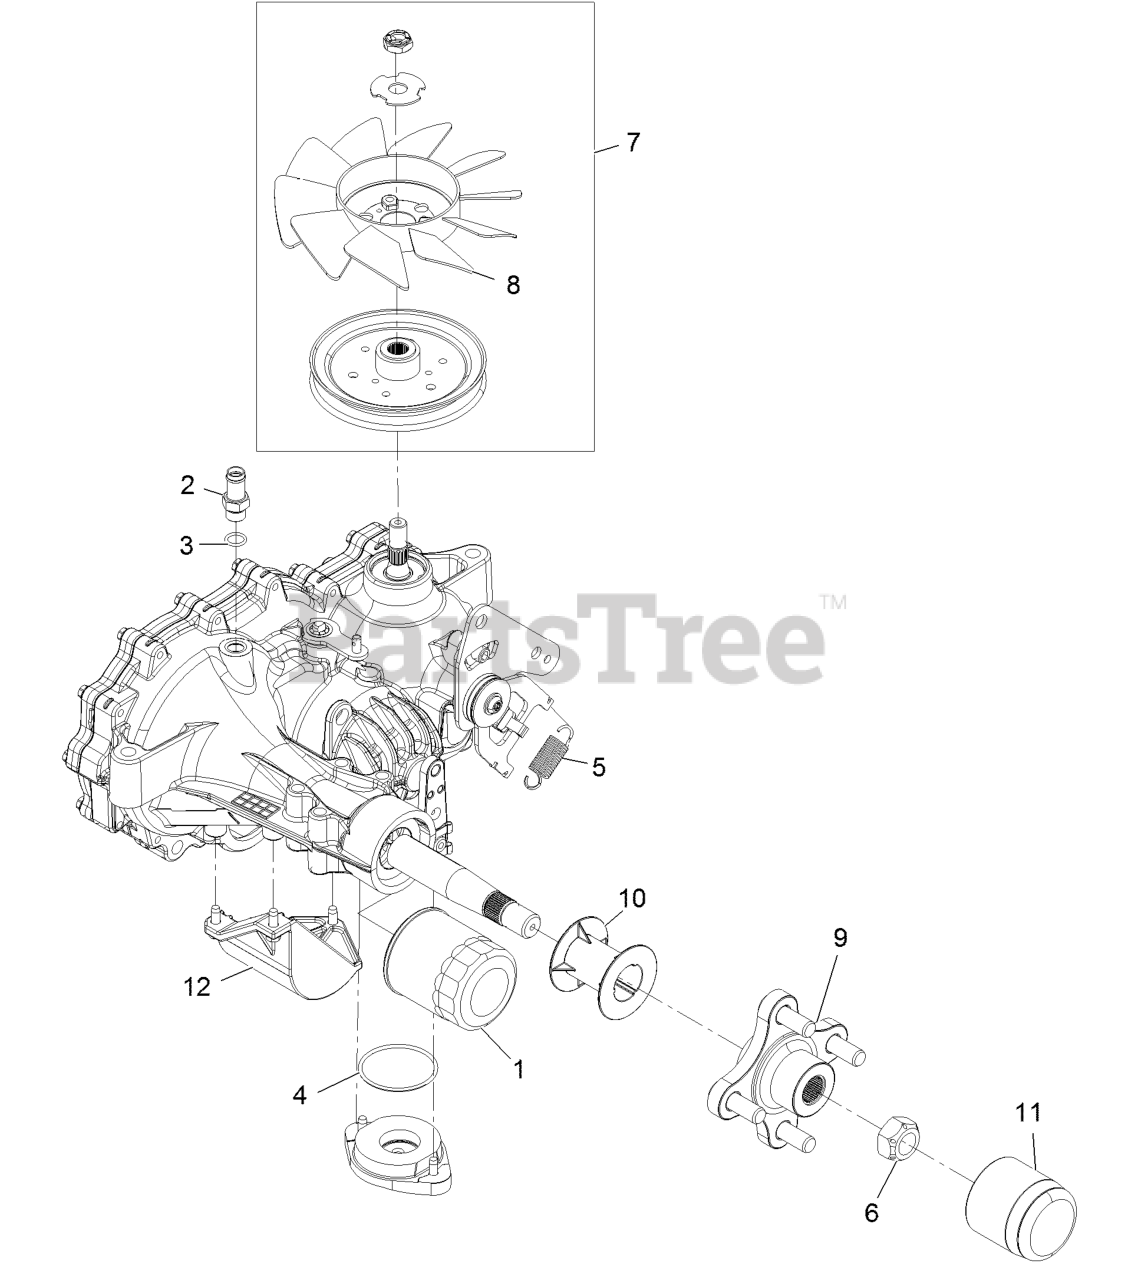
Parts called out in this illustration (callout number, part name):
1	ELEMENT-OIL FILTER, HYD
2	ADAPTER-STRAIGHT
3	O-RING
4	O RING-SEAL
5	SPRING-EXTENSION
6	NUT-HUB
9	HUB-OFFSET
10	TUBE-AXLE
11	CAP-AXLE, LONG
12	GUARD-FILTER, LH
